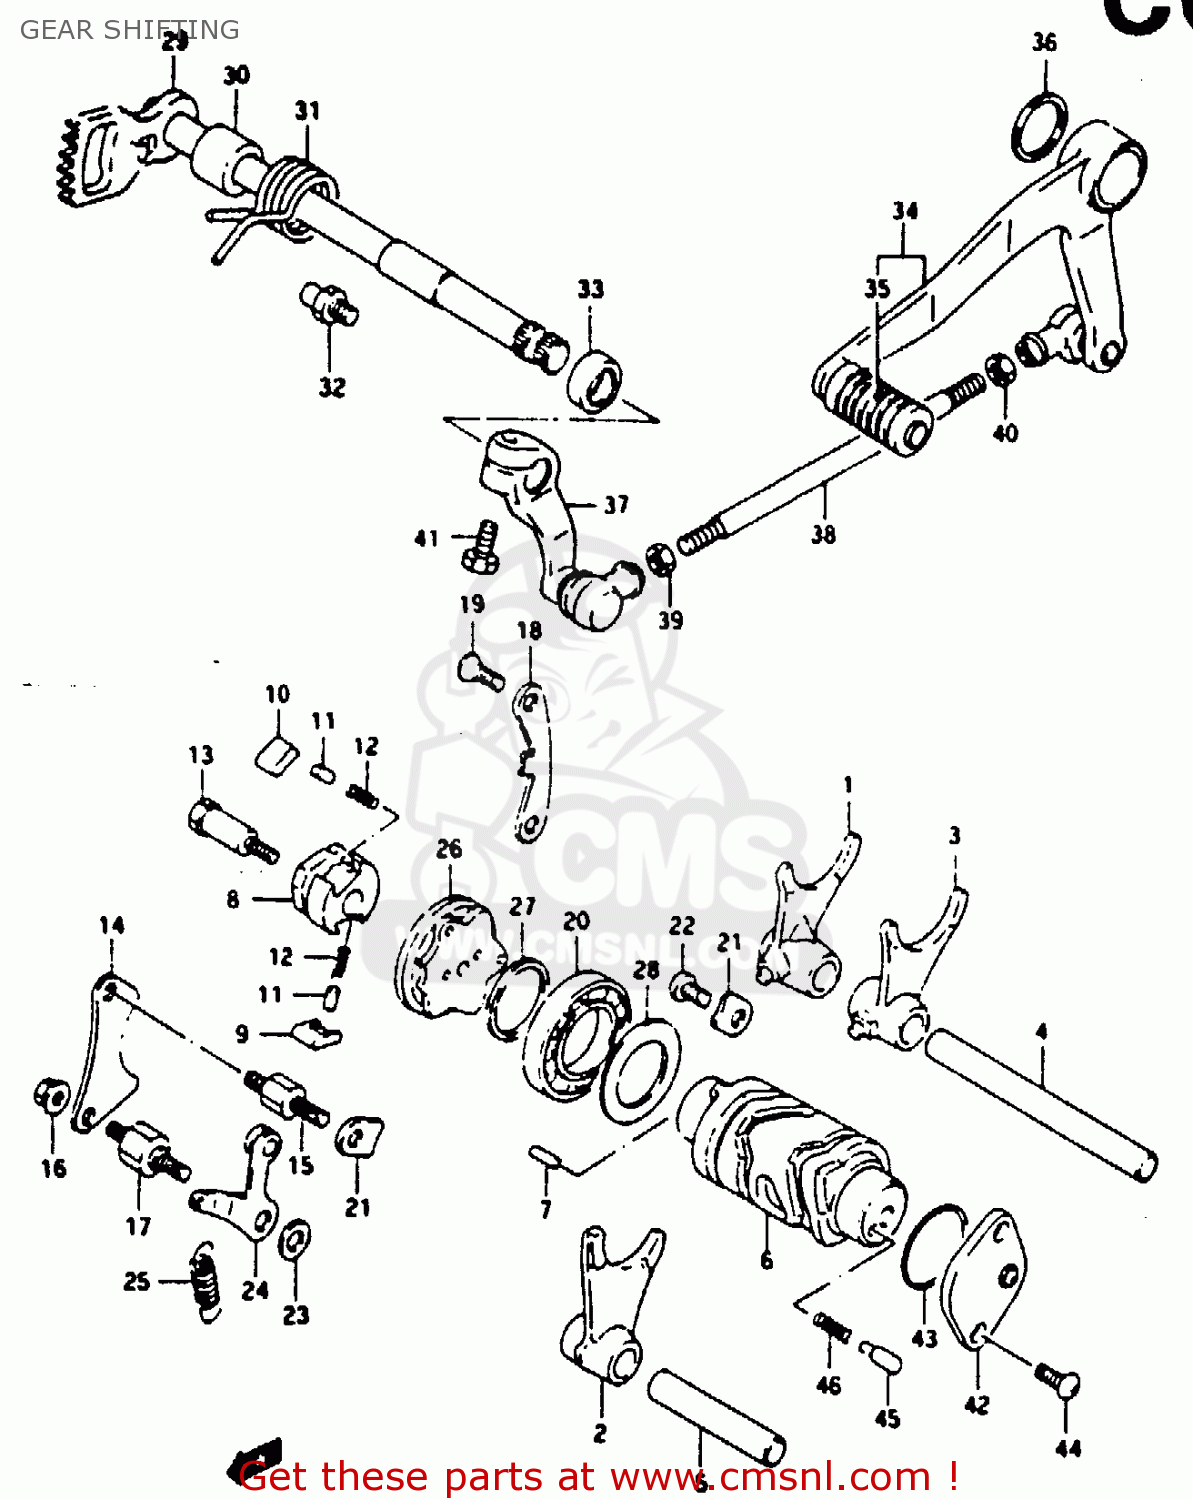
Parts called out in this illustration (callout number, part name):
1	FORK,GEAR SHIFT NO.1
2	FORK,GEAR SHIFT NO.2
3	FORK, NO. 3
4	SHAFT,GEAR SHIFT FORK(L:109)
5	SHAFT,GEAR SHIFT FORK
6	CAM
7	PIN
8	GEAR,GEARSHIFT CAM DRIVE
9	PAWL,GEAR SHIFT NO.1
10	PAWL,GEAR SHIFT NO.2
11	PIN(5X8)
12	SPRING
13	PIN,SHIFT CAM DRIVEN GEAR
14	LIFTER,GEAR SHIFT POLE
15	BOSS,SHIFT PAWL LIFTER
16	NUT
17	SUPPORT,CAM STOPPER ARM
18	GUIDE,GEAR SHIFT CAM
19	SCREW
20	BEARING
21	RETAINER,GEAR SHIFT CAM BRG
22	SCREW 6X12
23	WASHER
24	STOPPER, CAM
25	SPRING
26	PLATE,GEAR SHIFT CAM
27	WASHER(25X32X3)
28	SEAL,SHIFT CAM OIL
29	SHAFT,GEAR SHIFT
30	SPACER(12X20X15.3)
31	SPRING
32	STOPPER,GEAR SHIFT ARM
33	OIL SEAL
34	LEVER ASSY,GEAR SHIFT
35	RUBBER,GEAR SHIFT PEDAL
36	WASHER(18.2X27X1)
37	ARM,GEAR SHIFT LINK
38	ROD, GEAR SHIFT LINK (L:185)
39	NUT
40	NUT
41	BOLT
42	BODY,GEAR SHIFT SWITCH
43	O-RING (D:2.4 ID:26.2)
44	SCREW
45	PIN(5X15.5)
46	SPRING
